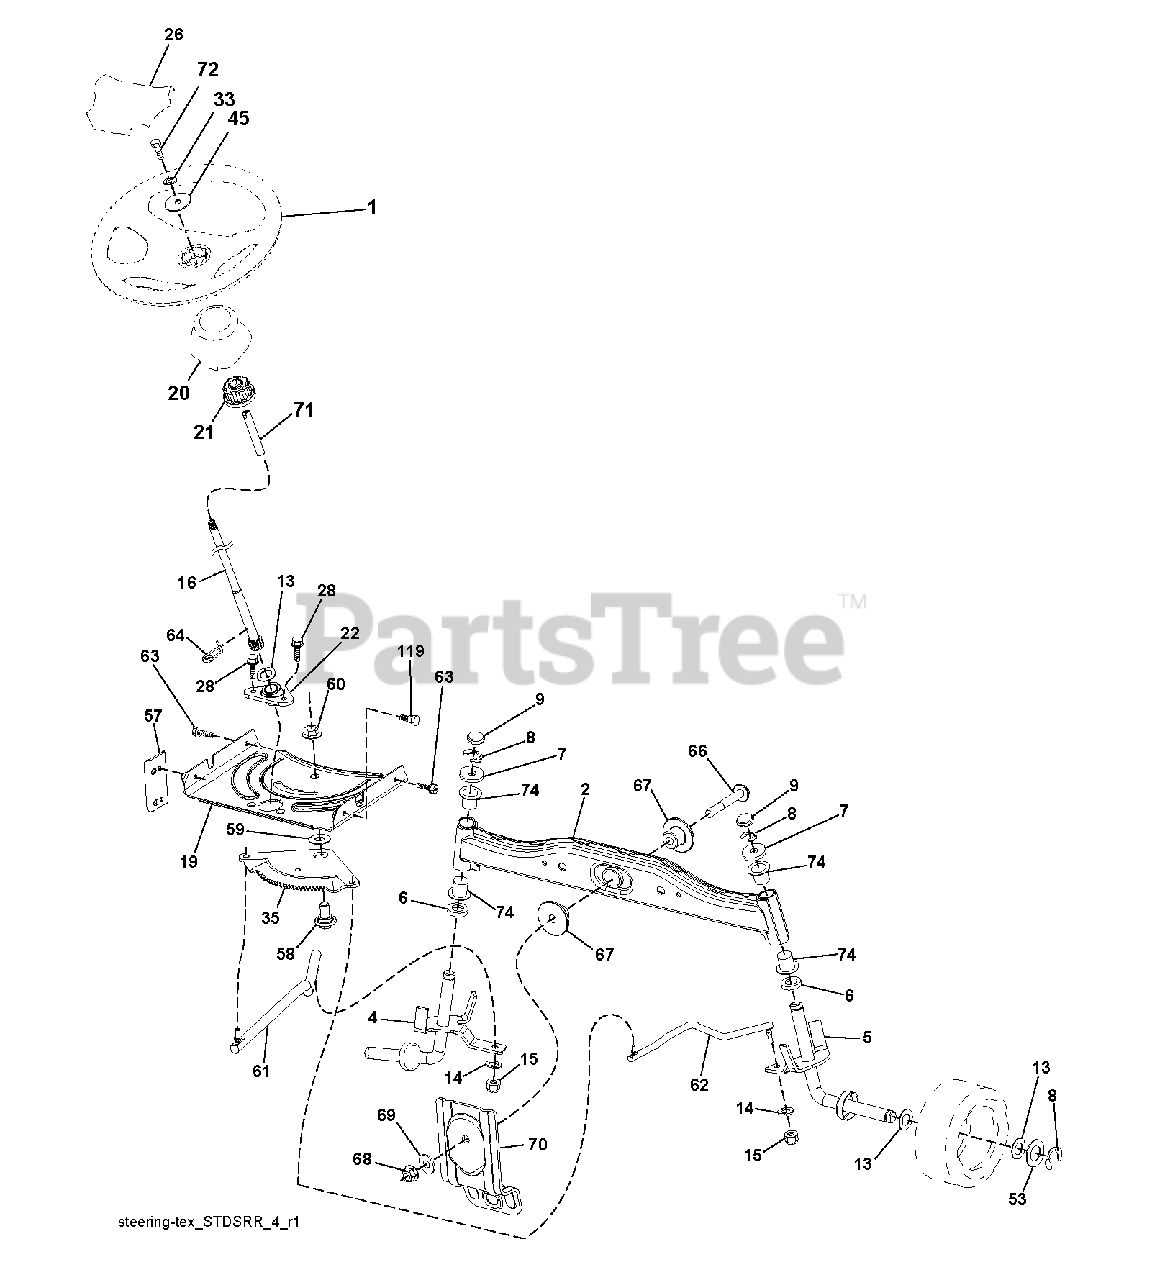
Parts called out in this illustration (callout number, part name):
1	WHEEL.STEERING.STDSRR.BLK/OV
2	AXLE HALF ASM-WELDED
8	RING CLIP
9	CAP.SPINDLE
14	WASHER, LOCK 3/8
15	NUT CROWNLOCK 3/8-24
16	SHAFT.STEER.3/4.PLATED.TEX
19	PLATE.STEER.DDL.NLT/NG
20	BOOT.STEERING.PREDATOR.LT.BLAC
21	ADAPTER, WHEEL STNG..
22	STEERING.SUPT.LOWER.
26	CAP.WHL.STRNG.STDSRRD.SRS.BLK
28	SCREW, 3/8-16X3/4
33	LOCKWASHER
35	GEAR.SECTOR.PLATE.DDL.
45	WASHER.11/32
53	WASHER.HARDENED
57	BRACKET.UPSTOP.TEX
58	BOLT.SHOULDER.SECTOR.P
59	WASHER.THURST.SECTOR.S
60	NUT FLANGE LOCK 5/8-11
61	DRAGLINK.LH.BALLSTUD.D
62	DRAGLINK.RH.BALLSTUD.D
63	SCREW
64	RETAINER.CLIP.SPRING.S
66	BOLT HEX FGHD 7/16-14 X 3 SERR
67	BUSHING.PM.FRONT AXLE
68	NUT.LOCK.FLANGE.7/16
69	WASHER.1.5X.505X.118
71	SHAFT.EXTEN.STRG.SPLINE
72	BOLT 5/16-18 X 4 W/PATCH
74	BRNG T
119	SHOULDER BOLT 5/16-18TT
